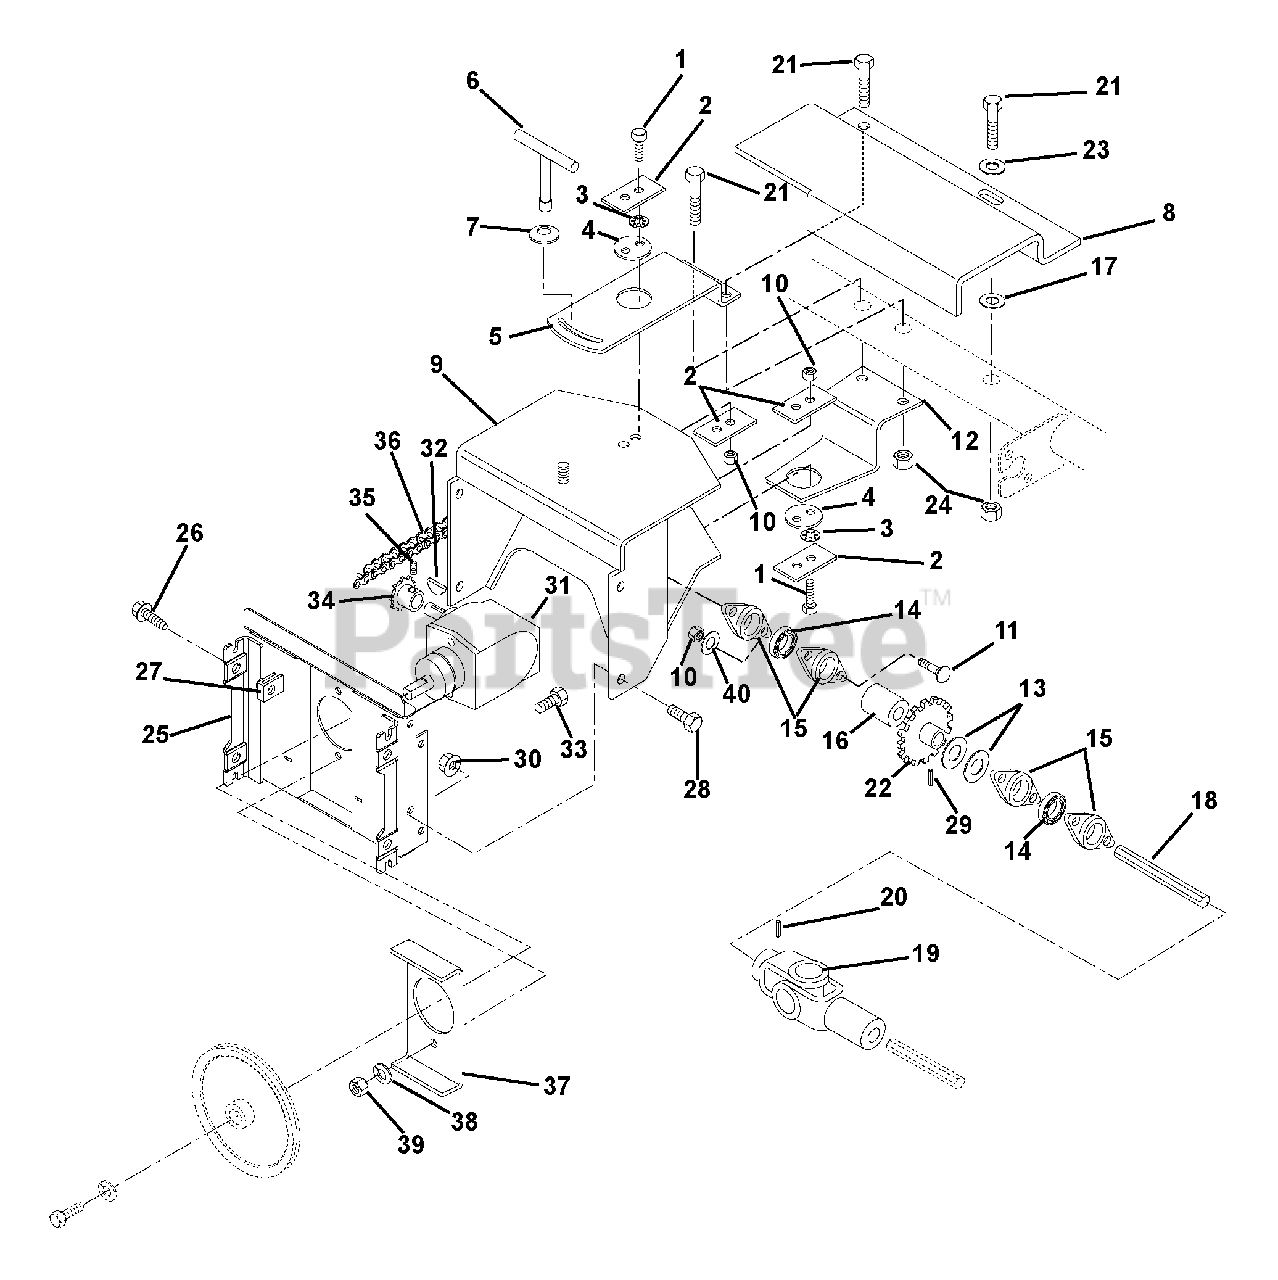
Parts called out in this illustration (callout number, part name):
1	@BLT-HEX .31-18X1.25 GR5 YWZC
2	RETAINER
3	@WSHR-LK-EXT.326X.599X.031YWZC
4	PIVOT CENTER
5	PLATE, TOP MOUNT
6	T-LOCK HANDLE
7	WSHR-BLVL .669X1.535X.138
8	GUARD, SHAFT
9	FRAME, ADAPTOR
10	@NUT-LK-CTR .31-18 YWZC
11	@BLT-RDHDSQNK .31-18X.75 G5YZ
12	PLATE, BOTTOM MOUNT
13	WSHR-FL-STL 1.015X1.500X.125
14	BRG-BALL .884HEXX52MMX1.07
15	BEARING FLANGE
16	SPACER 1.006X1.307X.500
17	WSHR-FL-STL .390X.88X.18 YWZC
19	JOINT, UNIVERSAL
20	PIN-ROLL .188X1.50
21	@BLT-HEX .38-16X3.25 GR5 YWZC
22	SPROCKET
23	@WSHR-FL-STL.406X.812X.065 YWZ
24	@NUT-LK-CTR .38-16 YWZC
25	PLATE, MOUNTING-BROOM
26	BLT-SERHFWH .38-16X.75 YWZC
27	NUT-RETNR .38-16 TINRMAN
28	@BLT-HEX .38-16X.75 GR5 YWZC
29	PIN-ROLL .188X1.75
30	@NUT-LK-CTR .38-16 YWZC
31	GEAR BOX ASSEMBLY
32	KEY-WDRF .188X.75X.313 SAE 9
33	@BLT-HEX .38-16X1.25 GR5 YWZC
34	SPROCKET
35	SCR-SET .25-20X.38 SKHCUPNL OH
36	ROLLER CHAIN #41 - 34 PITCHES
37	PLATE, STIFFENER
38	@WSHR-LK .38X.094 REG YWZC
39	@NUT-HEX .38-16 YWZC
40	@WSHR-FL-STL.38X.875X.083 YWZC
